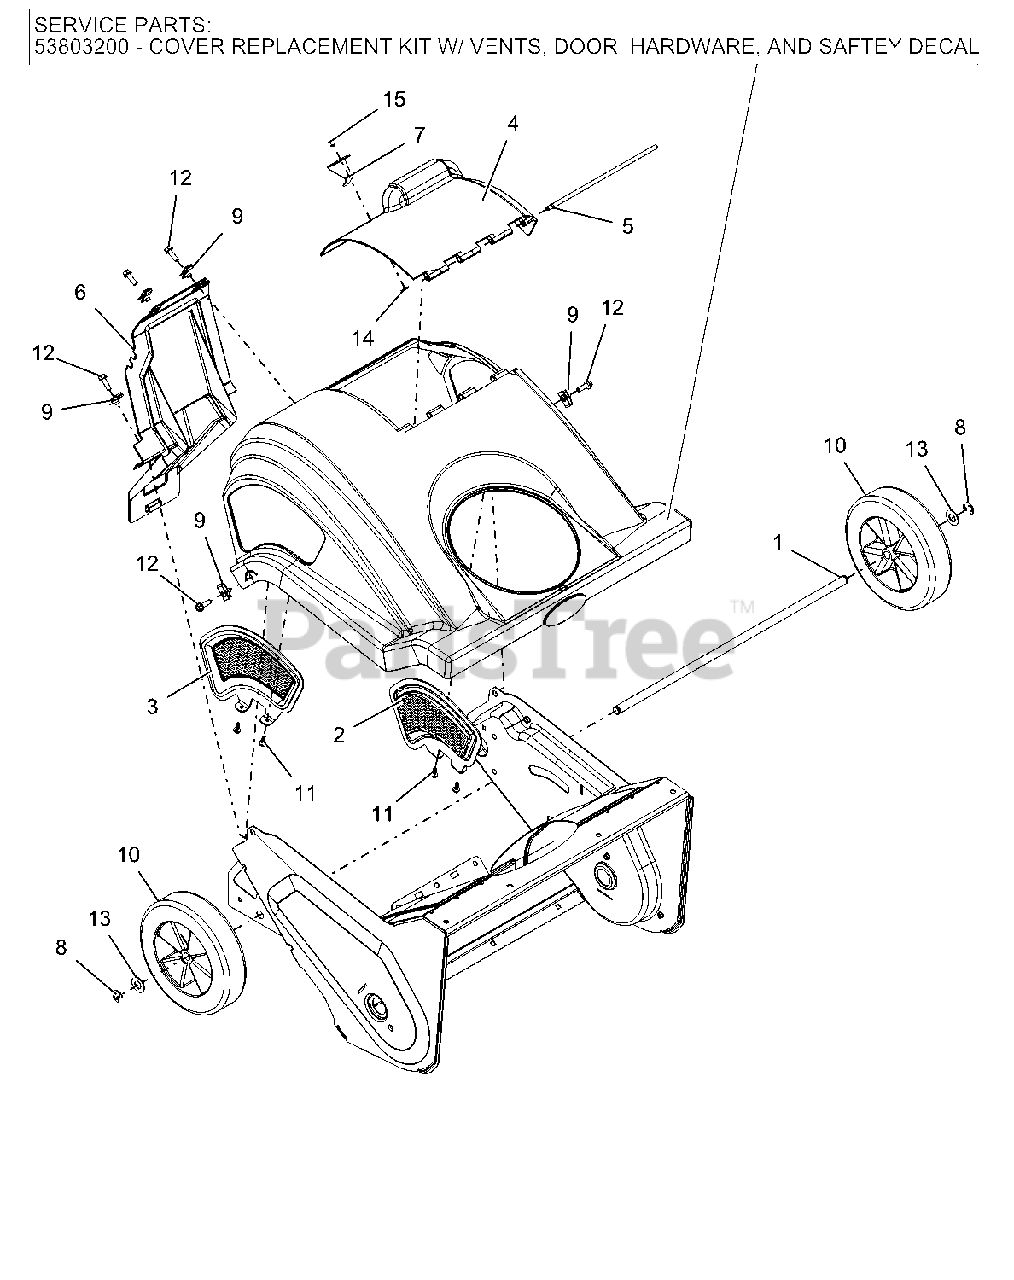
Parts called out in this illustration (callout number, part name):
1	SHAFT, AXLE
2	VENT, COVER LEFT
3	RIGHT VENT, COVER
4	DOOR, COWEL COVER
5	ROD, COVER, SINGLE STAGE
6	BACK COVER, NON ELEC. START
7	TAB, LATCH
8	RG-RTNG-EXT .500X.042 (E)
9	NUT-RTNR .25-20X.56
10	WHL 7.50" .50 BORE, 1.50 HUB
11	SCR-TAP #10X.50 BOSS INDHXHD
12	BLT-HEX .25-20X.75 HWH YZ GR5
13	WSHR-FL-STL.531X1.00X.063 YWZC
14	WSHR-FL-STL .196X.500X.06 YZ
15	RVT-POP .187 YZ
16	KIT, COWL REPLACEMENT
